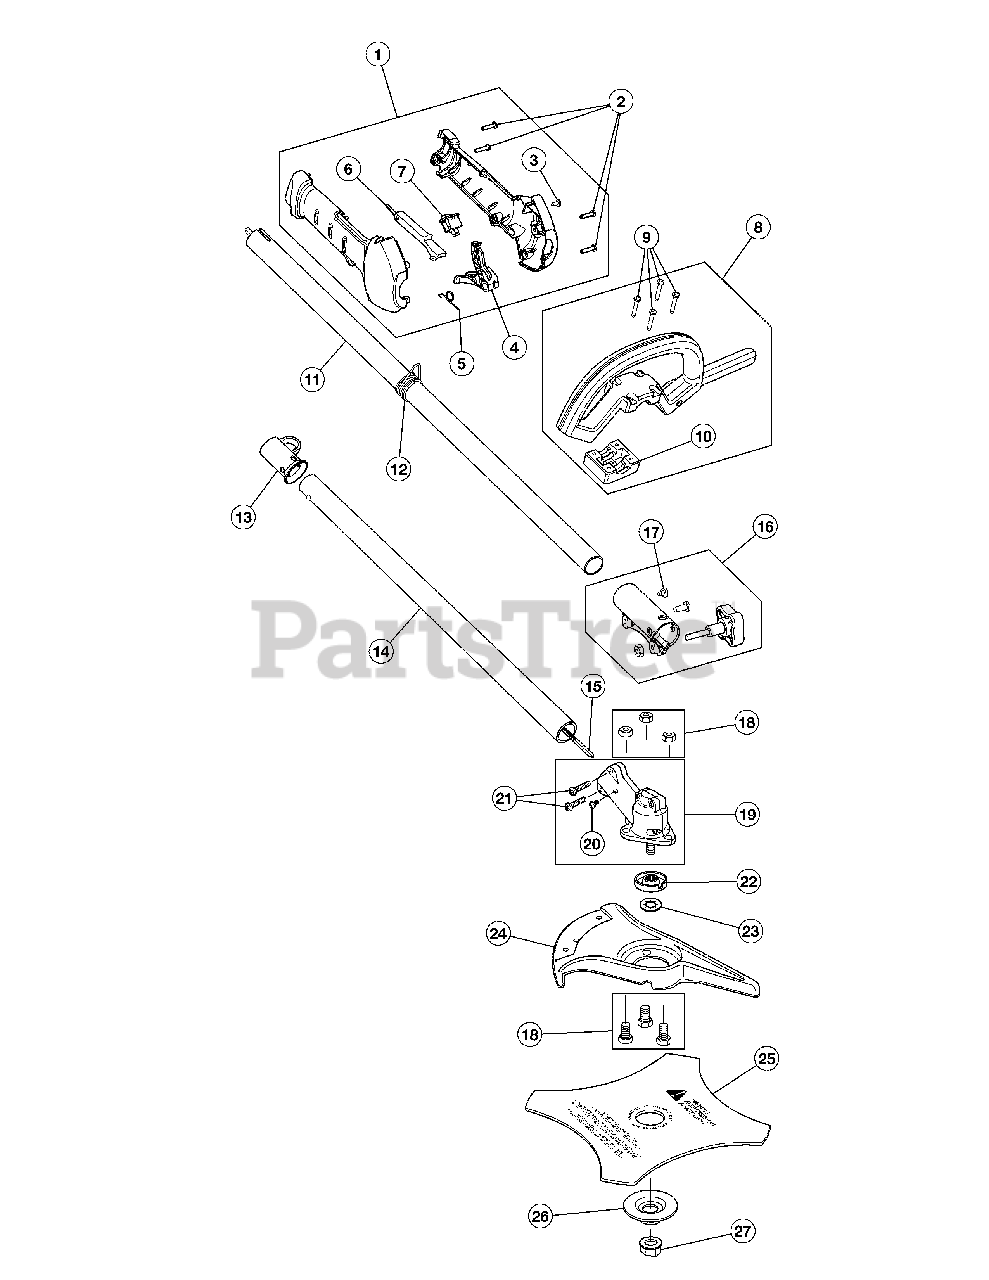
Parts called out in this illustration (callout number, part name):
1	Throttle Grip Assembly (Incl. 2 - 7)
3	Anti-Rotation Screw
4	Throttle Trigger
5	Throttle Trigger Spring
8	D-Handle Assembly (Incl. 9)
10	D-Handle Base
11	Upper Drive Shaft Assembly
12	Harness Clip
14	Lower Drive Shaft Housing Assembly
15	Lower Flexible Drive Shaft
16	Split Boom Coupler Assembly
18	Shield Mount Screw Assembly
19	2 Piece Gearbox Assembly
20	Anti-Rotation Screw
21	Gearbox Mounting Hardware
22	Blade Driver
24	Blade Shield/Shield Mount
25	4-Tooth Blade
26	Retaining Washer
